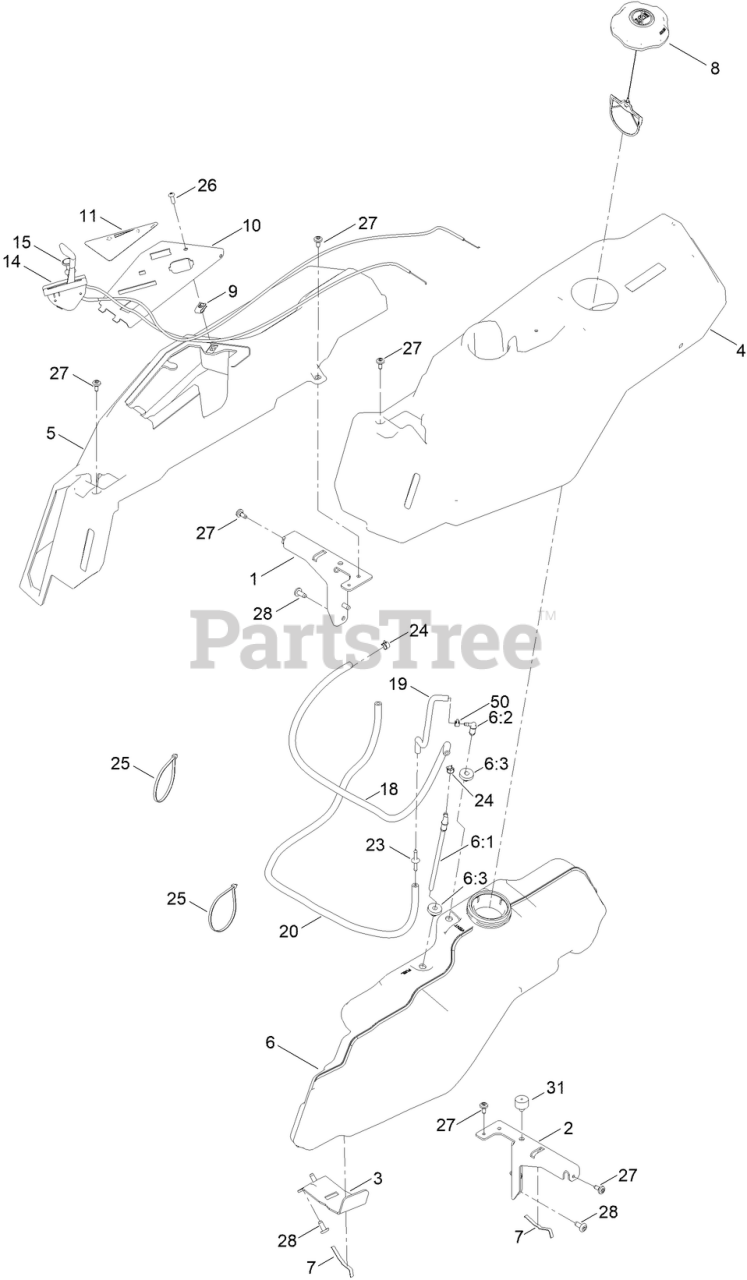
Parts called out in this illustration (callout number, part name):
1	SUPPORT-POD, RH
2	SUPPORT-POD, LH
3	SUPPORT-TANK, FUEL
4	POD-LH
5	POD-RH
6	TANK-FUEL ASM
6:1	CONNECTOR-ELBOW, 90 DEG
6:2	FITTING-ELBOW 90
6:3	BUSHING
7	SPRING
8	CAP-FUEL, RATCHETING
10	PANEL - CONTROL
11	DECAL-PANEL, CONTROL
14	CABLE-THROTTLE
15	CABLE-CHOKE
18	HOSE-FUEL
19	HOSE-FUEL
20	HOSE-FUEL
23	ADAPTER ORIFICE
24	CLAMP-HOSE
25	TIE-CABLE
26	SCREW-PRH
27	SCREW-SHOULDER
31	BUMPER-GROMMET
50	CLAMP-HOSE
